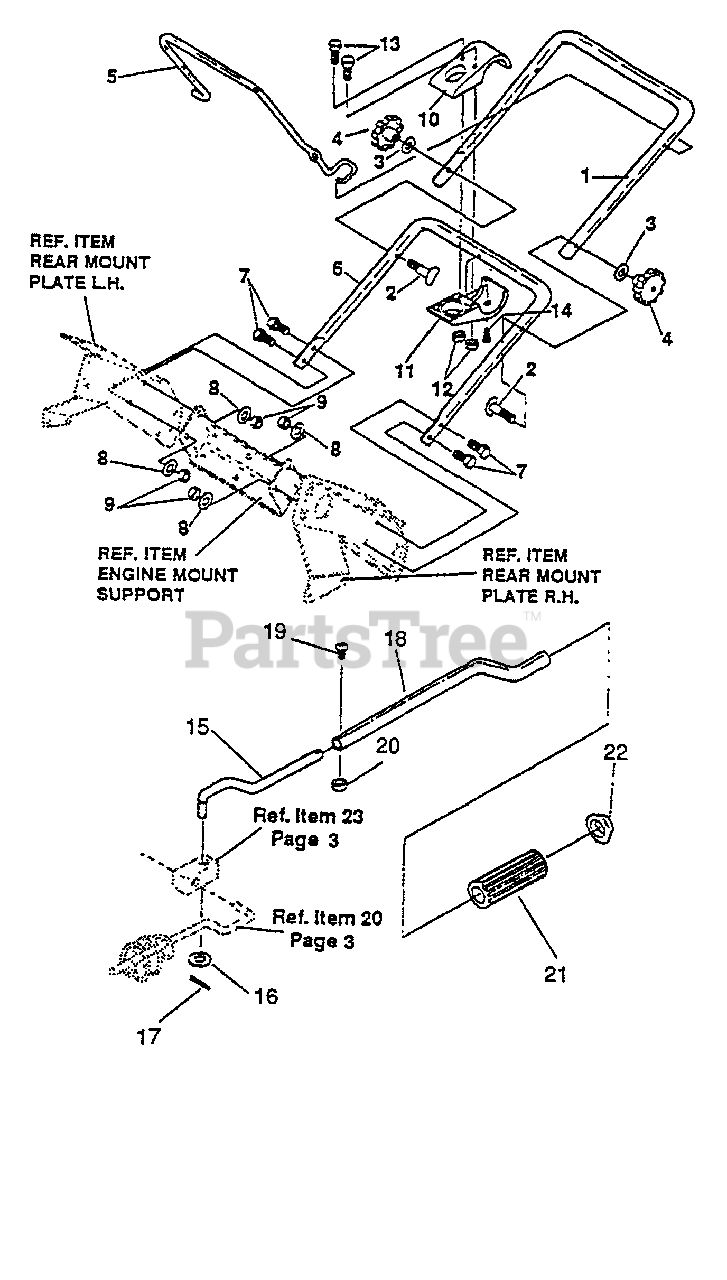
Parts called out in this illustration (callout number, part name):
1	HANDLE - UPPER
2	BOLT, 5/16-18 X 1-3/4"
3	WASHER
4	KNOB
5	BAR, DRIVE CONTROL LOOP
6	HANDLE - LOWER
7	SCREW - 5/16-18 X 3/4"
8	WASHER
9	NUT - 5/16-18
10	BRKT HALF, CHUTE CRANK
11	BRKT HALF, CHUTE CRANK
12	LOCKNUT - 10-24
13	SCREW - 10-24 X 1.00"
14	SCREW - 1/4-20 X .63" -- TAPPING
15	ROD, CHUTE CONTROL MIDDLE
16	WASHER - .390 X .75 X .031
17	PIN, SPLIT
18	ROD, UPPER CHUTE CONTROL
19	SCREW - 10-32 X 7/8"
20	LOCKNUT - 10-32
21	KNOB, CHUTE, CRANK
22	NUT - CAP
